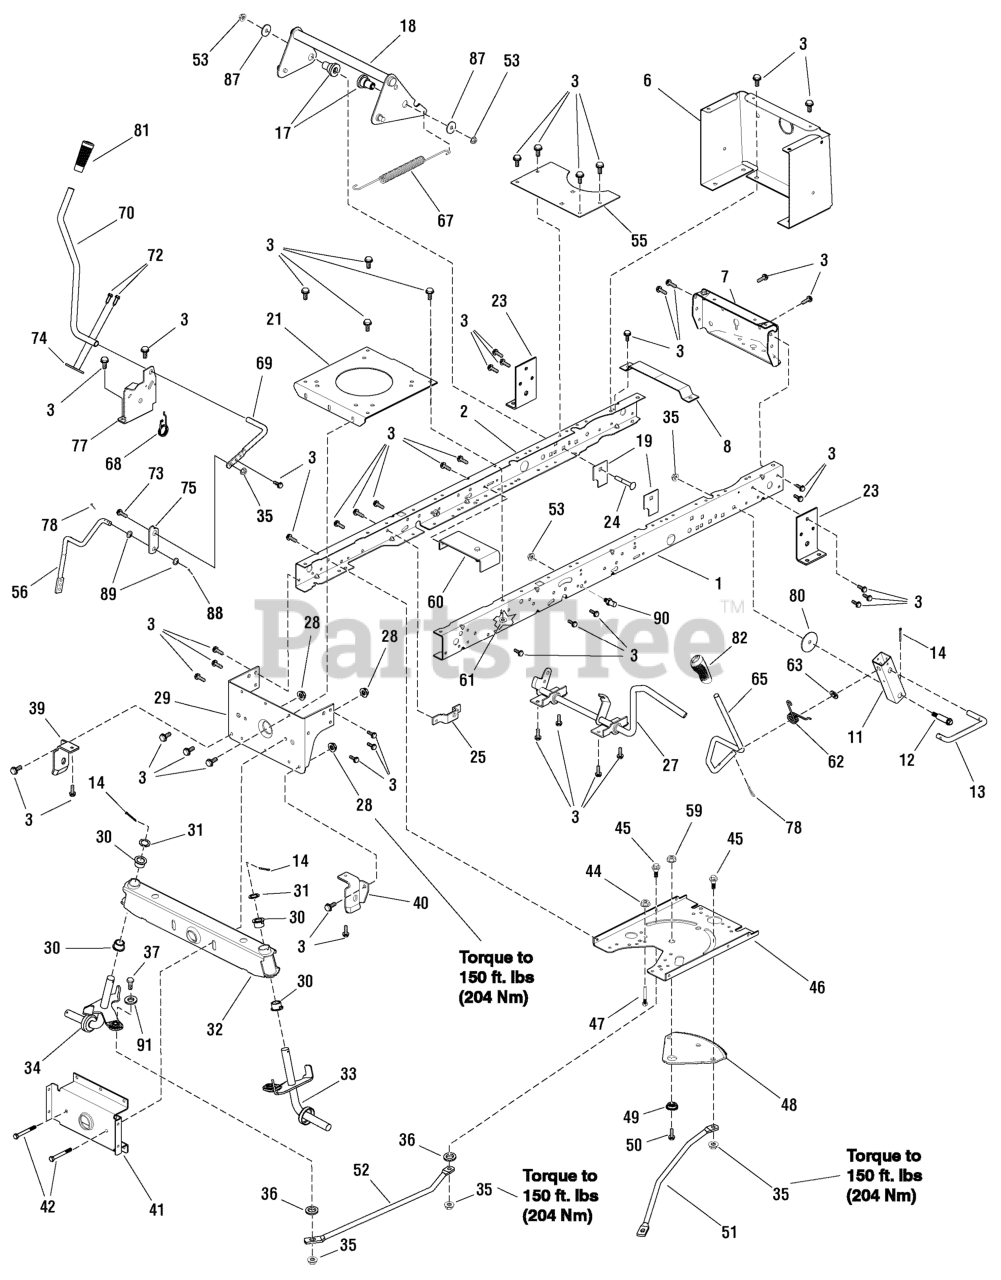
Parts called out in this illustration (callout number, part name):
1	FRAME, Left
2	FRAME, Right
3	CAPSCREW, 5/16-18 x 3/4
4	SCREW, Hex 1/4 x 1/2
6	PANEL, Rear
7	PLATE, Hitch
8	BRACKET, Battery Support
11	BRACKET, Pivot
12	BOLT, Shoulder, 3/8-16 x 1/2
13	LINK, Lift Handle
14	COTTER PIN, 1/8 x 1-1/4
17	SPACER, Lifter
18	LIFTER ASSEMBLY
19	PLATE, Stiffening
21	PLATE, Engine
23	BRACKET, Transaxle
24	BOLT, Carriage, 3/8-16 x 2-1/2
25	BRACKET, Bellcrank
27	BRAKE PEDAL
28	NUT, Hex Flange, 5/16-24
29	BRACKET, Rear Hanger
30	BEARING, Spindle, LT
31	WASHER, Flat
33	SPINDLE, Left
34	SPINDLE, Right
35	NUT, Hex Flange 3/8-16
36	WASHER, Flat 3/8
37	BOLT, Hex 3/8-16 x 1-1/2
39	HANGER, Right Deck
40	HANGER, Left Deck
41	AXLE, Hanger
42	BOLT, Hex Head, 5/16-24 x 2-3/4
43	SECTOR GEAR ASSEMBLY
44	NUT, Hex Flange, 5/16-18
45	BOLT, Shoulder, 3/8-16 x 1
46	PLATE, Steering Mount
47	SCREW, Guide
48	GEAR, Sector
49	BEARING, Sector Gear
50	CAPSCREW, Hex Head, 5/16-18 x 1
51	DRAG LINK, Left
52	DRAG LINK, Right
53	NUT, Hex Flange, 3/8-16
54	SCREW, 3/8-16 x 3/4
55	PLATE, Idler Pulley
56	CRANK, PTO
59	NUT, Flange, 5/16-18
60	ASSEMBLY, Idler Bracket (secondary)
61	NUT, Hex Flange, 5/16-18
62	SPRING, Torsion
63	WASHER, Flat, 1
65	HANDLE, Lift
67	SPRING, Extension
68	SPRING, Torsion, PTO
69	LEVER, PTO
70	HANDLE, PTO
72	SCREW, Thread Forming, 1/4-20 x 1
73	BOLT, Shoulder, 3/8-16 x 1/2
74	PADDLE, Switch, Yellow
75	LINK, PTO, Yellow
77	BRACKET, PTO
78	HAIRPIN
80	WASHER, Plain, 2-1/4
81	GRIP, PTO
82	GRIP, 1/2" Shaft, Tapered
87	WASHER, Flat, 3/4
88	COTTERPIN, 3/4
89	WASHER, Flat 3/4
90	PIN, Threaded Shoulder, 3/8-16 x 1-1/2
91	WASHER, FLAT, 25/64" ID X 1" OD X 14 GA.
